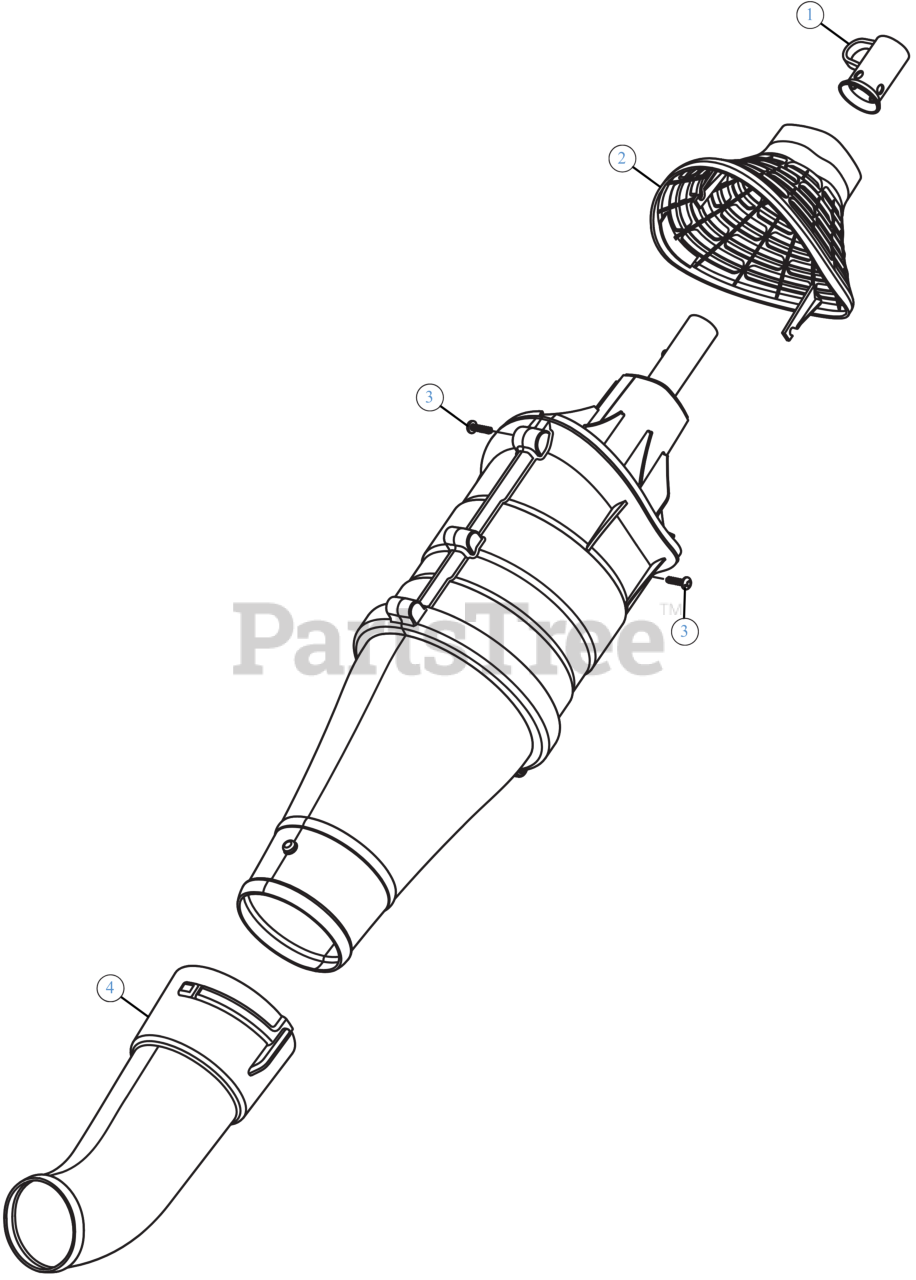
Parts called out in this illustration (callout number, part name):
1	HANGER
2	INTAKE BLOWER ATTACH
3	SCREW 8-16 x 3/4
4	NOZZLE BLOWER ATACH
